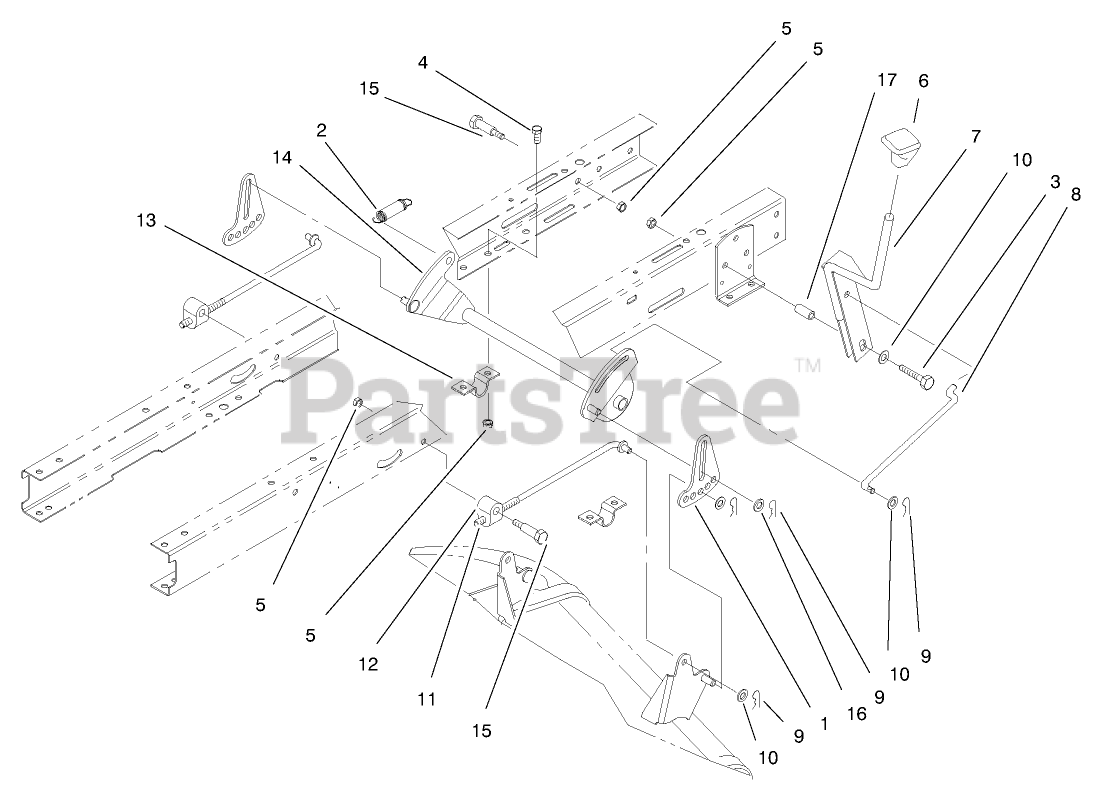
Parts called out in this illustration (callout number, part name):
2	SPRING-EXTENSION
3	SCREW-HH
4	SCREW-HH
5	NUT-LOCK, NI
6	KNOB-SHIFT
8	LINK-HOC
10	WASHER-FLAT
11	ROD-HANGER, REAR
12	TRUNNION-HOC
13	CLAMP-PIVOT, HOC
15	SCREW-SHOULDER, HH
16	WASHER-HARDENED
17	SPACER
